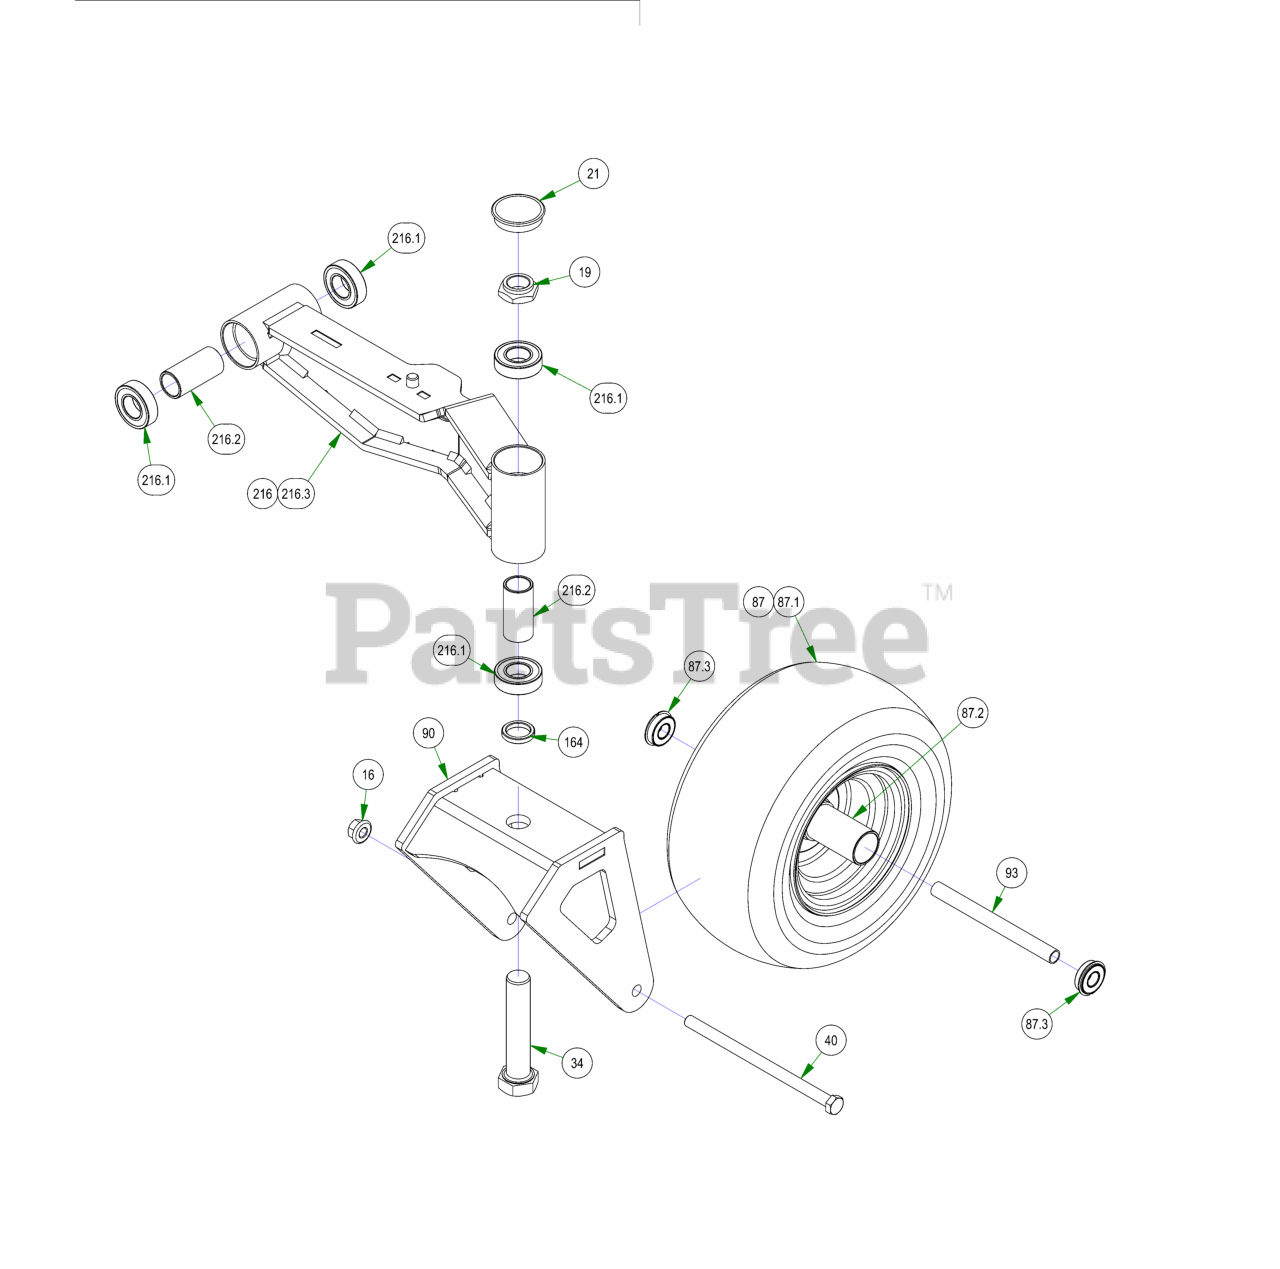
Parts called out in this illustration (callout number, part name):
16	1/2-13 NYLON INSERT FLANGE LOCKNUT ZINC
19	1"-14 NYLON INSERT JAM LOCKNUT ZINC
21	2017 Bearing Cover
34	1"-14 X 5 HEX CAP SCREW (GR.8) ZINC YELLOW
40	1/2-13 X 8-1/2 HEX CAP SCREW (GR.5) ZINC
87	13x6.5-6 Black Tire and Wheel Assembly
87.1	13 x 6.50 - 6 Tire
87.2	Front Tire Rim
87.3	Ball Bearing w/Retainer, 99502H-NR, .625 Bore x 1.375 OD x .4375 Width
90	2019 Stand-on Front Fork Weldment
93	Front Wheel Spanner
164	Spacer, 1x1.375x.25
216	2021 Maverick LH Front Suspension Arm Assy (48", 54" & 60")
216.1	1641 BEARING W/2 CONTACT RUBBER SEALS
216.2	2016 Front Bearing Spacer
216.3	2021 Maverick I-Beam Front Arm LH Weldment - Painted
